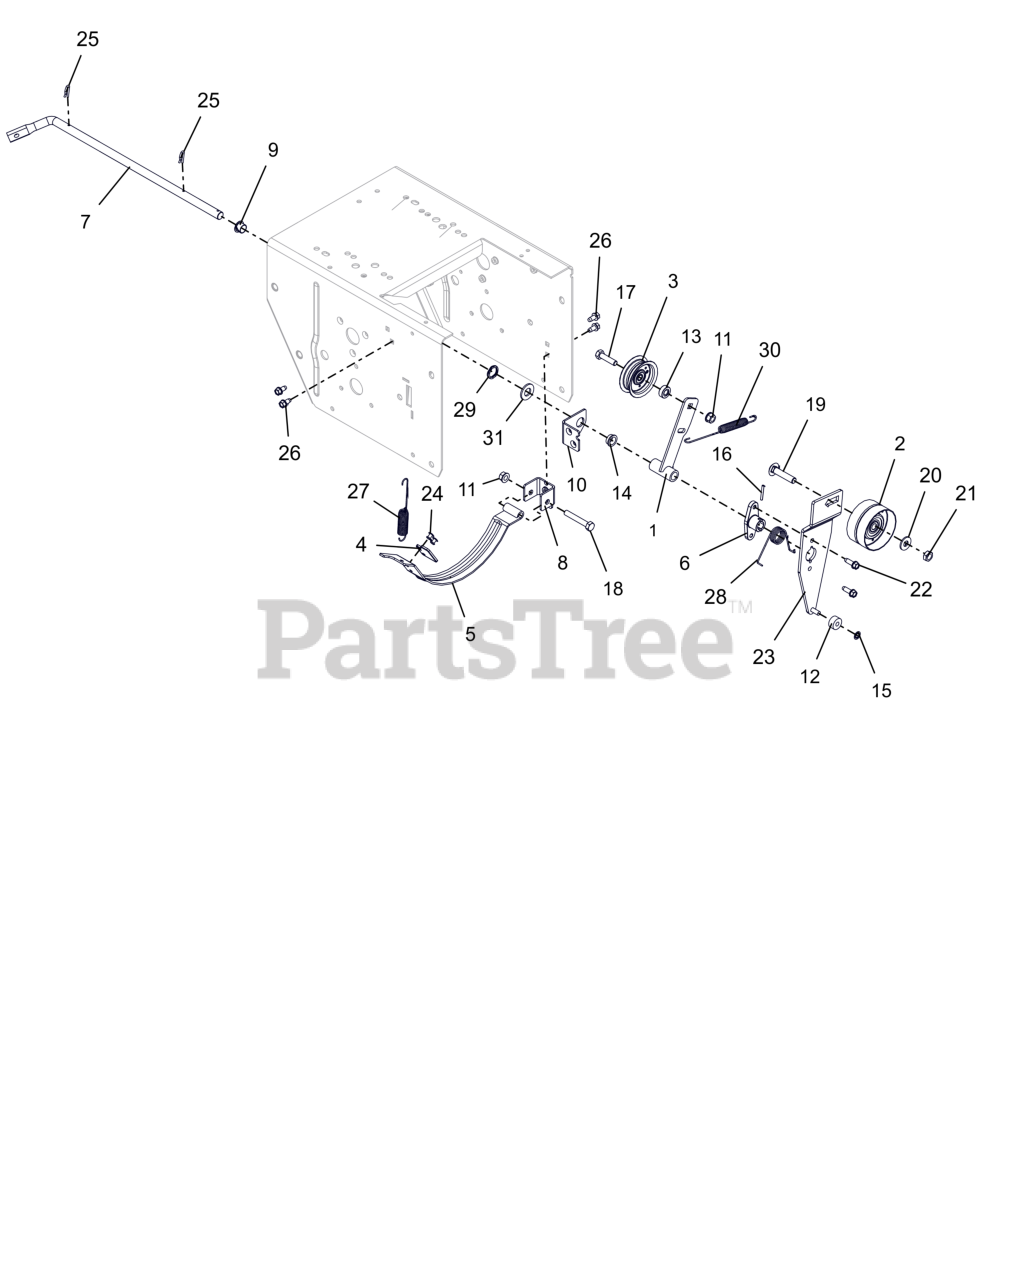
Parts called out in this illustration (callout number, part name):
1	ARM, IDLER-TRACTION
2	IDLER, FLAT-2.75 OD X .375 ID
3	IDLER, FLAT - 2.00"
4	PAD, BRAKE
5	ARM, BRAKE-ATTACHMENT
6	HUB, BRAKE ARM
7	ARM, ATTACHMENT
8	PIVOT, BRAKE
9	BUSHING, POLYLINER-.50 SPLIT
10	BRACKET, SUPPORT
11	NUT-LK-TOP-FLG .312-18 GF ZCC
12	BSHG,SLV .265 X .625 X .375
13	SPCR, BRG .315X.500X.358X.281
14	BSHG,FLANGE .500X.625X.270X.75
15	RG-RTNG-EXT .250X.010
16	PIN-ROLL .125X1.00
17	BLT, HEX .31-18X1.25 G5 ZCC
18	BLT, HEX .31-18X2.00 G5 ZCC
19	BLT, RHSSN .38-16X1.75 G5 ZCC
20	WSHR,FLT .375X.875X.083 ZCC
21	NUT-LK-CTR-JAM .375-16 GB ZCC
22	SCR,TAP .25-20X.75 HWH TR ZCC
23	ARM, IDLER - ATTACHMENT
24	RVT, POP .1875 ZCC
25	CLIP, SPRING
26	SCR-TAP .25-20X.50 HWH ZCC
27	SG-TENS .056X.60X4.40
28	SG-TORS .067X.88
29	WAVE SPRING .600X.875X.25FH
30	SG-TENS .06X.482X5.35
31	WSHR,FLT .531X1.062X.095 ZCC
